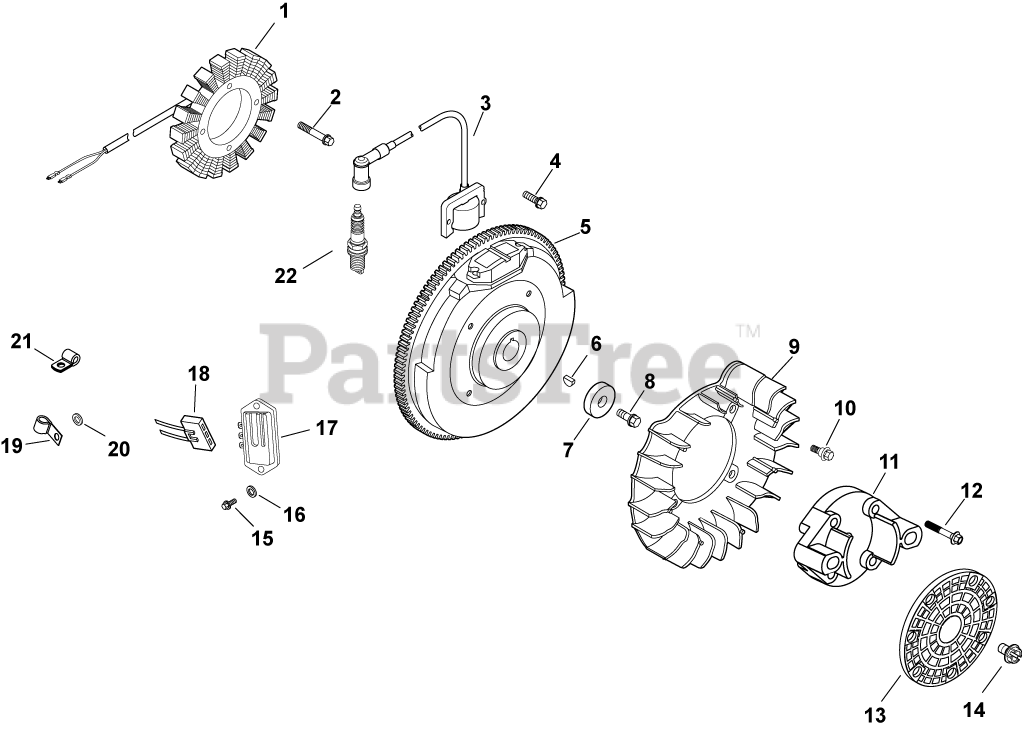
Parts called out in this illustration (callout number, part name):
1	KIT, 15 / 20 AMP STATOR
2	SCREW, M5X0.8X25 - (#25086402S)
3	KIT, MODULE IGNTN (CDI FIXED)
4	SCREW, FLG THD FRM M5X.8X20-(#25086399S)
5	FLYWHEEL, PAINTED-USE 24 025 55-S
6	KEY, 3/16" X 5/8"
7	WASHER, FLAT 13/32"
8	SCREW, FLG M10X1.5X45 - (#25086361S)
9	FAN USE 24 755 253-S
10	BOLT, SHOULDER
11	ADAPTER, DRIVE SHAFT
12	SCREW, FLG M8X1.25X45
13	SCREEN,GRASS LOW PRFILE W/HOLE
14	SCREW, SEMS DOG POINT
15	SCREW, PHL HD #11-16X7/8"
16	WASHER, FLAT 3/16"
17	REG/RECT-15 AMP (KM)-USE 41 403 10-S
18	CONNECTOR, BODY (KM)-USE 25 155 41-S
19	CLIP, CABLE
20	WASHER, FLAT 1/4" (O.D. 1/2")
21	CLIP, TUBE & WIRING (KM)
22	SPARK PLUG, RFI
